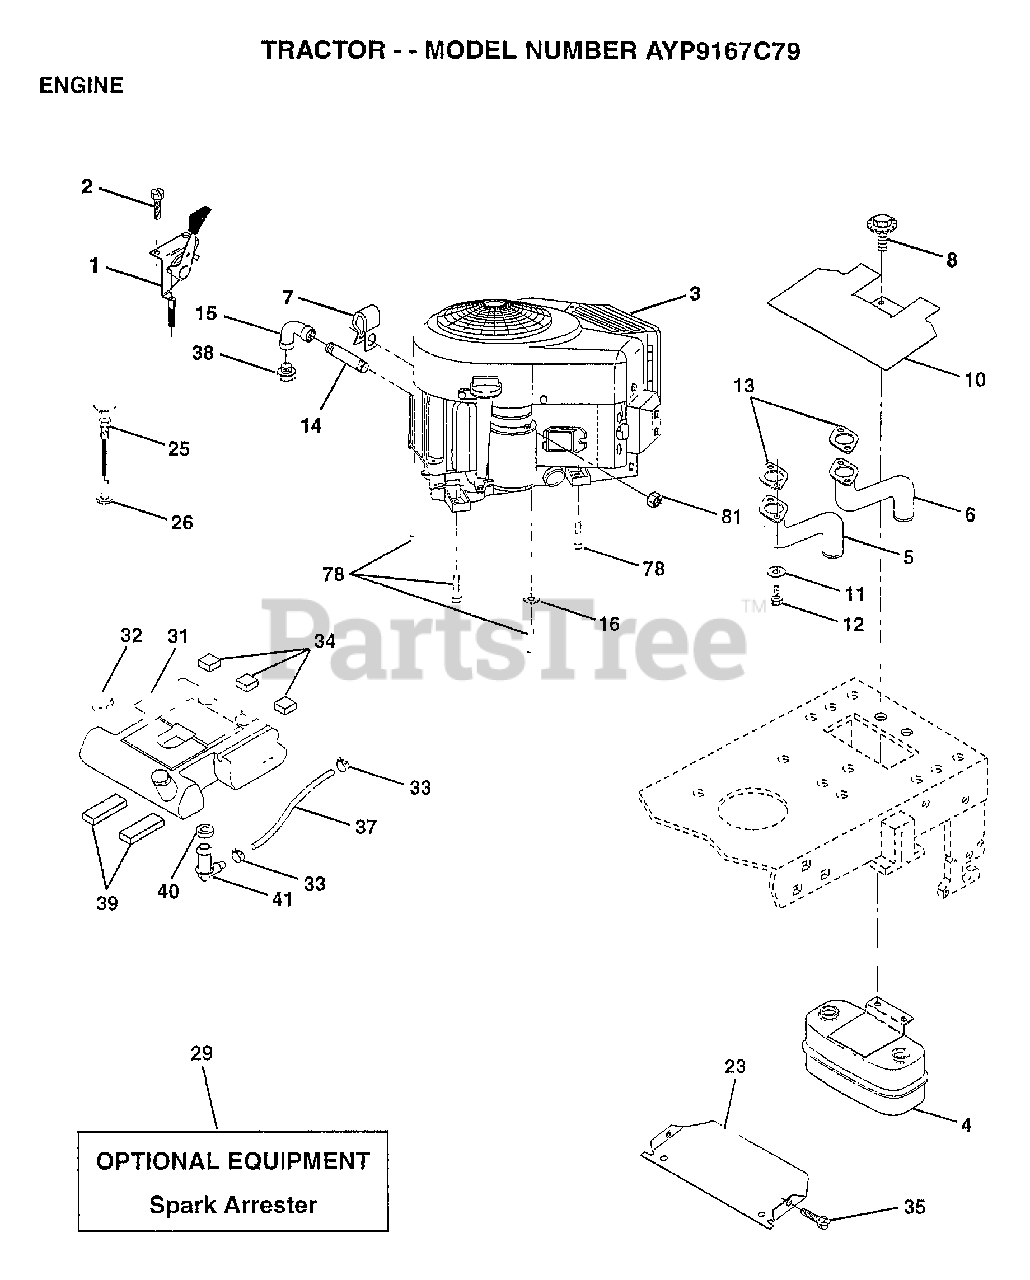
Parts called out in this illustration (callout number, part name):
1	CONTROL THROT. LH
2	SCREW LT
4	MUFFLER.TW.LOTONE
5	TUBE ASSY EXH LH
6	TUBE ASSY EXH RH
7	CLAMP.TUBE.DBL.EN
8	BOLT.5/16-18.UNC
10	SHIELD.HEAT.
14	PIPE NIPPLE LT
15	ELBOW
16	LOCKWASHER
23	SHIELD-HEAT
25	CONTROL.CHOKE.37
26	"NUT,KEPS 3/8-24IM"
31	TANK FUEL REAR
32	CAP ASM FUEL
33	HOSE CLAMP
34	PAD-SPACER LT
35	SCREW
37	FUEL LINE T
39	PAD IDLER TI
40	BUSHING OUTLET T
41	STEM.TANK.FUEL
78	SCREW
80	NUT
